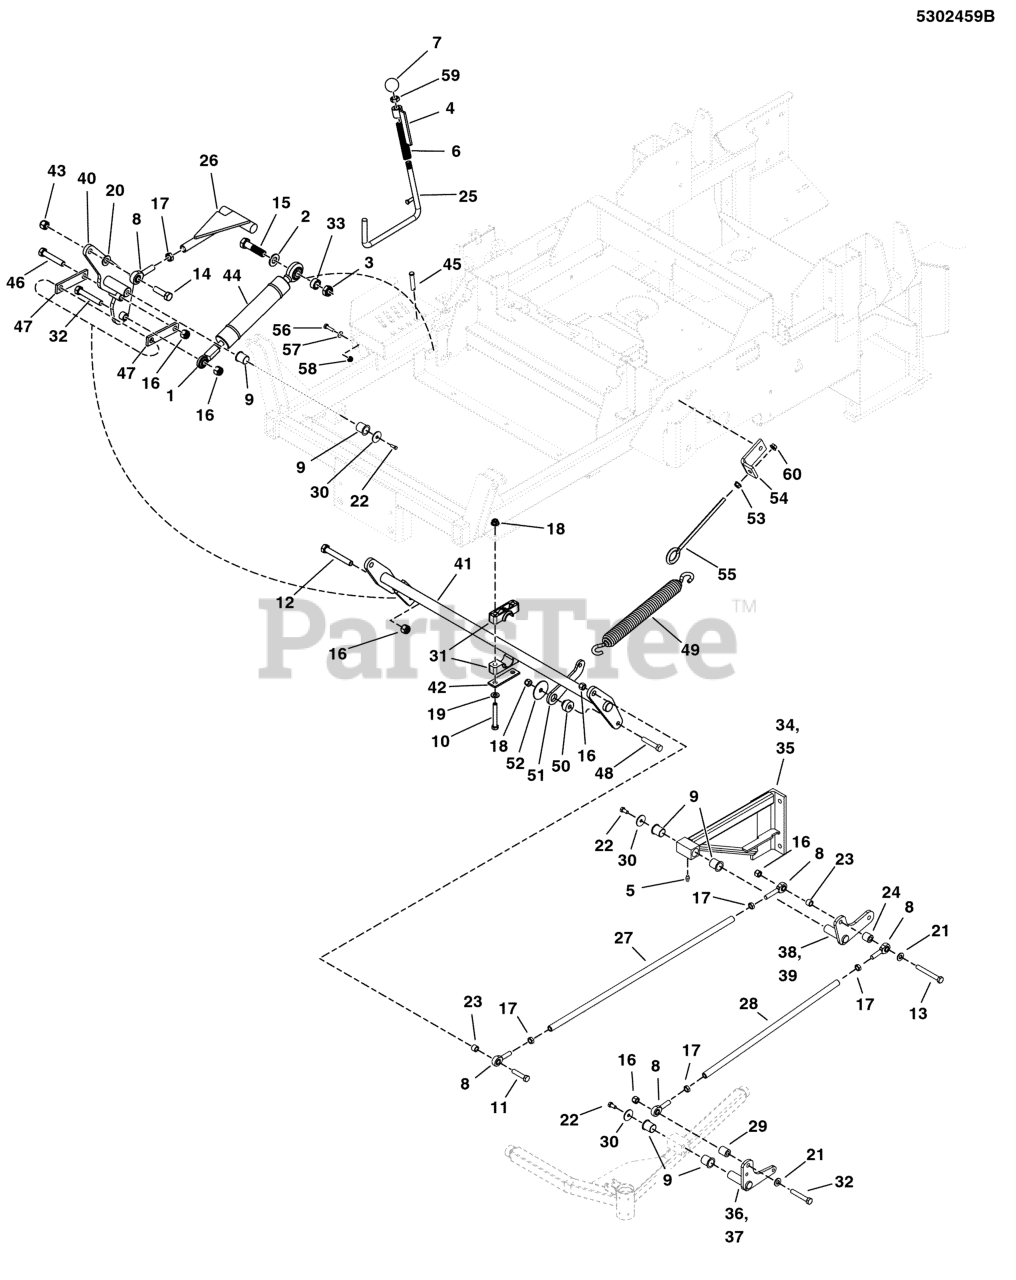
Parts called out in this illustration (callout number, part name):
1	JOINT-BALL .500-20 THD .500ID BLK PLT
2	WASHER, 5/8 SAE
3	NUT, 5/8-11 HEX JAM NYLON LOCK
4	WELD, LOCKOUT, LIFT LEVER - RED
5	GREASE FITTING, 1/4-28 STRAIGHT
6	SPRING-COMP, .615ID X 4.00LG X .080WR
7	KNOB, PLASTIC, 1/2-13
8	BALL JOINT, 1/2-20, MALE
9	BUSHING, 1.00 X 1.13 X 1.38, PLASTIC
10	BOLT, 3/8-16 X 2-3/4" GD5 CZ
11	BOLT, 1/2-13 X 2-1/4" GD5 CZ
12	BOLT, 1/2-13 X 3-1/2, HEX HD, GD5, CZ (SV)
13	BOLT, 1/2-13 X 4" GD5 CZ
14	BOLT, 1/2-20 X 1-3/4" GD8 CZ
15	BOLT, 5/8-11 X 2-1/2 GD5, CZ
16	NUT, 1/2-13 HEX NYLON LOCK
17	NUT, 1/2-20 HEX JAM
18	NUT, 3/8-16 HEX NYLOCK FLANGE
19	WASHER, 3/8 SAE
20	WASHER, 1/2 SAE
21	WASHER, 1/2 GD9 YZ
22	BOLT, 3/8-16 X 3/4, PLT W/PATCH
23	SPACER, .51 X .75 X .56, CZ
24	SPACER, .52 X 1.00 X 1.00
25	WELD, ROD DECK LIFT
26	WELD, DECK HEIGHT LINK, IS5100Z - RED
27	ROD, DECK LIFT INNER
28	ROD, DECK LIFT OUTER
29	SPACER, .52 X 1.00 X 1.15
30	WASHER, .390 X 1.50 X .109, YZ
31	PIVOT BLOCK, PLASTIC
32	BOLT, 1/2-13 X 3" GD5 CZ
33	SPACER, .64 X 1.00 X .50, CZ
34	WELD, REAR DECK LIFT, LH
35	WELD, REAR DECK LIFT, RH
36	WELD, DECK LIFT LEVER, LH - BLK
37	WELD, DECK LIFT LEVER, RH - BLK
38	WELD, DECK LIFT LEVER, RH - RED
39	WELD, DECK LIFT LEVER, LH - RED
40	WELD LIFT ASSIST IS5100Z - RED
41	WELD DECK LIFT SHAFT IS5100 - RED
42	PLATE, PIVOT BLOCK SUPPORT - BLK
43	NUT, Hex, Nylon Lock, 1/2-20
44	CYLINDER
45	PIN-CLEVIS, 1/2 X 2-1/2 YZP
46	BOLT, 1/2-13 X 2-3/4 GD5 CZ
47	LINK, DECK LIFT, IS5100Z
48	BOLT, 3/8-16 X 2, GD5, CZ
49	SPRING-EXT, 1.393 ODX13.25LGX.218WR, BLK
50	BUSHING, DECK PIVOT
51	LINK, SPRING
52	WASHER, .39 X 2.00 X X .14
53	NUT, 3/8-16 HEX
54	ANCHOR, EYEBOLT
55	EYE BOLT, 3/8-16 X 6, 1 EYE
56	BOLT, 1/4-20 X 1" GD5 CZ
57	WASHER, 1/4 SAE
58	NUT, 1/4-20 HEX NYLOCK FLANGE
59	NUT, 1/2-13 HEX JAM
60	NUT, 3/8-16 HEX NYLON LOCK
